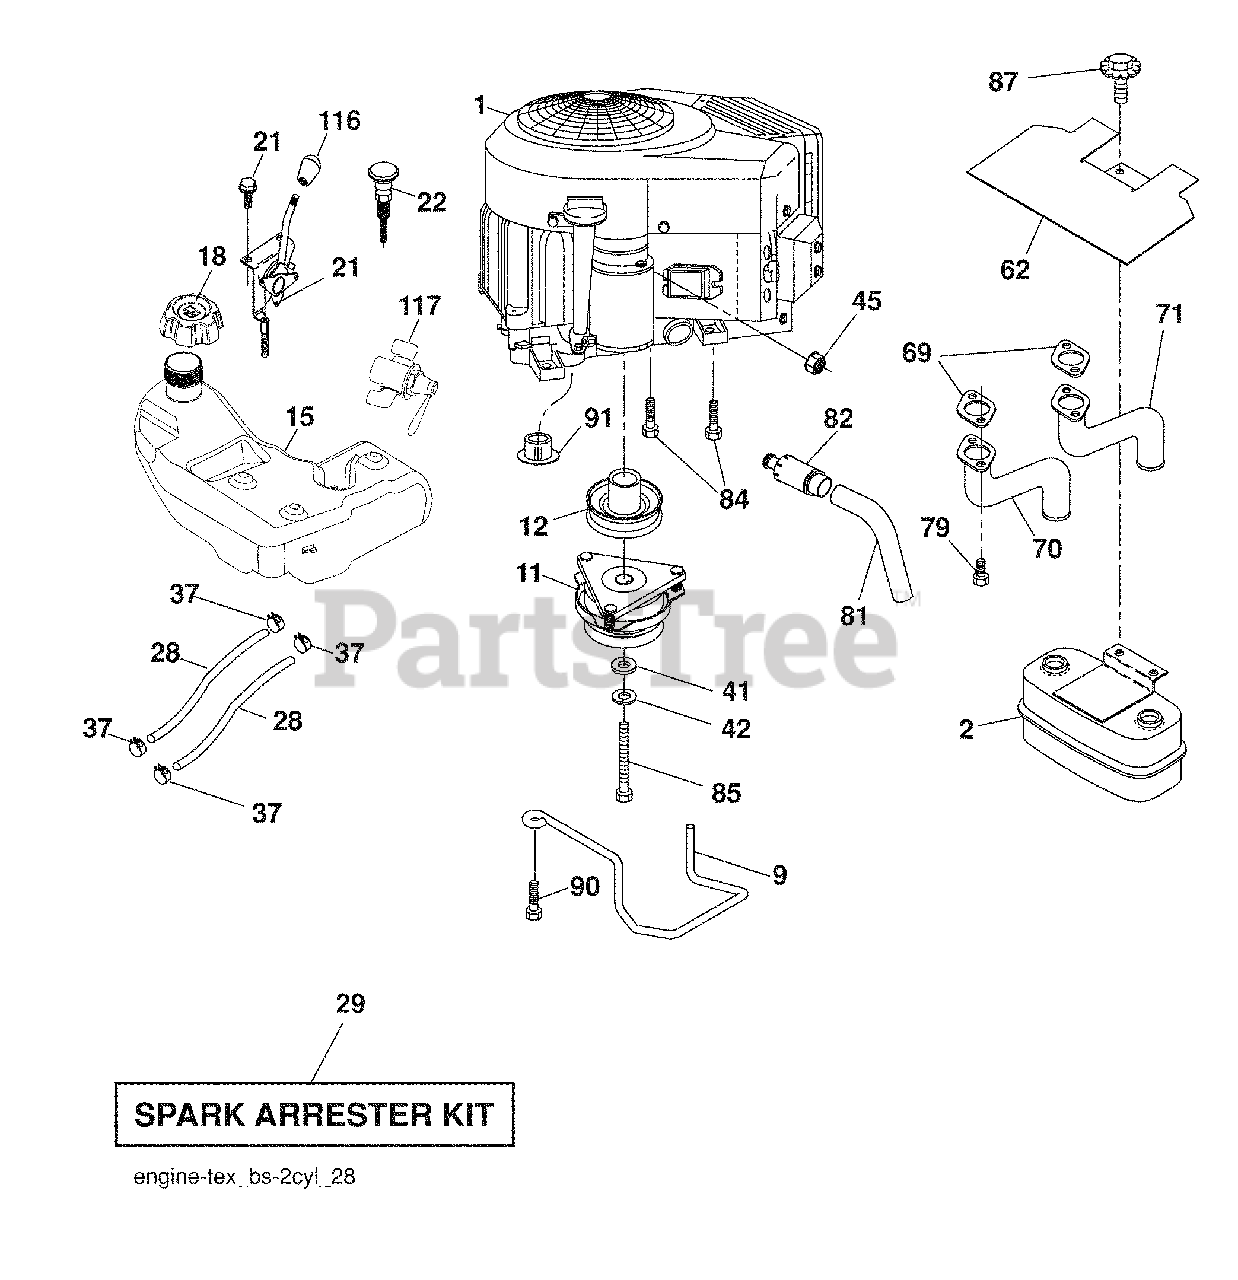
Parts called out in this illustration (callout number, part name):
9	Keeper Asm. Belt Engine
11	Clutch Electric
12	Pulley Engine
15	Tank Fuel 4.0
18	Cap Asm
20	Control Throttle
21	Screw #10 x 0.750 BOS Thread
22	Control Choke
28	Fuel Line
29	Spark Arrester Kit
37	Clamp Hose
41	Washer 1-1/2 OD x 15/32 ID x .250
42	Washer Lock 7/16
45	Nut Keps Hex 1/4-20 unc
62	Shield Heat Muffler
70	Tube Exhaust LH
71	Tube Exhaust RH
79	Screw Tube Muffler
81	Tube Drain Oil Easy
82	Plug Drain Oil Easy
84	Screw 3/8-16 x 1-1/4
85	Bolt 7/16-20 x 3.75 Gr. 5
87	Bolt 5/16-18 unc x 1 w/Sems
90	Screw 3/8-16 x 1
116	Knob
117	Valve Fuel Reserve
